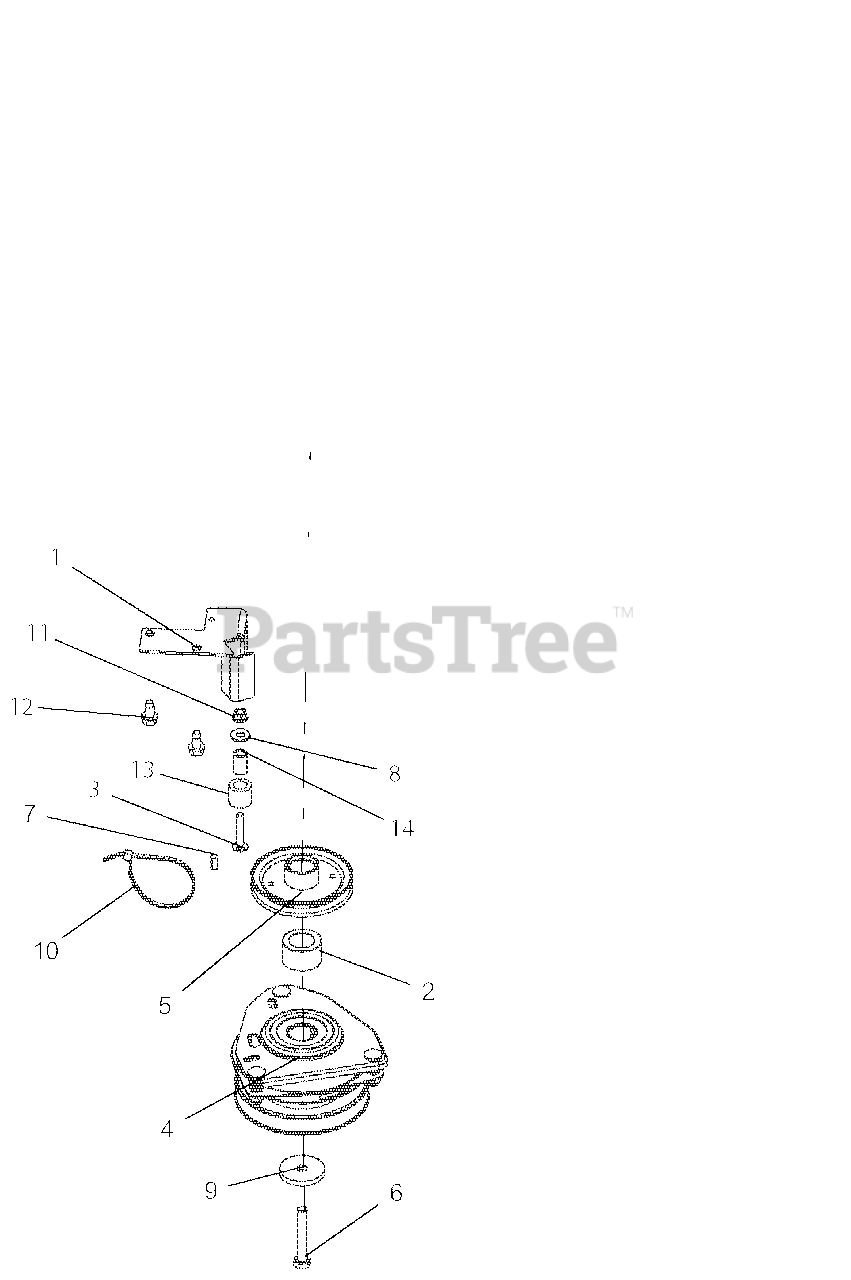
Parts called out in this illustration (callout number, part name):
1	BRKT, CLUTCH STOP (BLACK)
2	SPCR, 1.125 C 1.750 X 1.060
3	BLT-RDHDSQSHNK .31-18X1.75 YWZC
4	CLUTCH, OGURA GT1A-EH01
5	PULLEY, 4.50 OD X 1.127 ENGINE-BLACK
6	BLT-HEX .44-20X2.75 GR5 EP80 YWZC
7	KEY-SQ .250X.250X.625
8	WSHR-FL-STL.38X.875X.083 YWZC
9	WSHR-FL-STL .469X2.00X.25 YWZC
10	CABLE, TIE 5.50 LG
11	NUT-LK-NYL-FLG .31-18 YWZC
12	SCR-TAP .38-16X.75 HWH TR YWZ
13	BUMPER, RUBBER .62 X 1.0 X .88 LG
14	BUSH.,S.391X.622X.95 ST REV A
